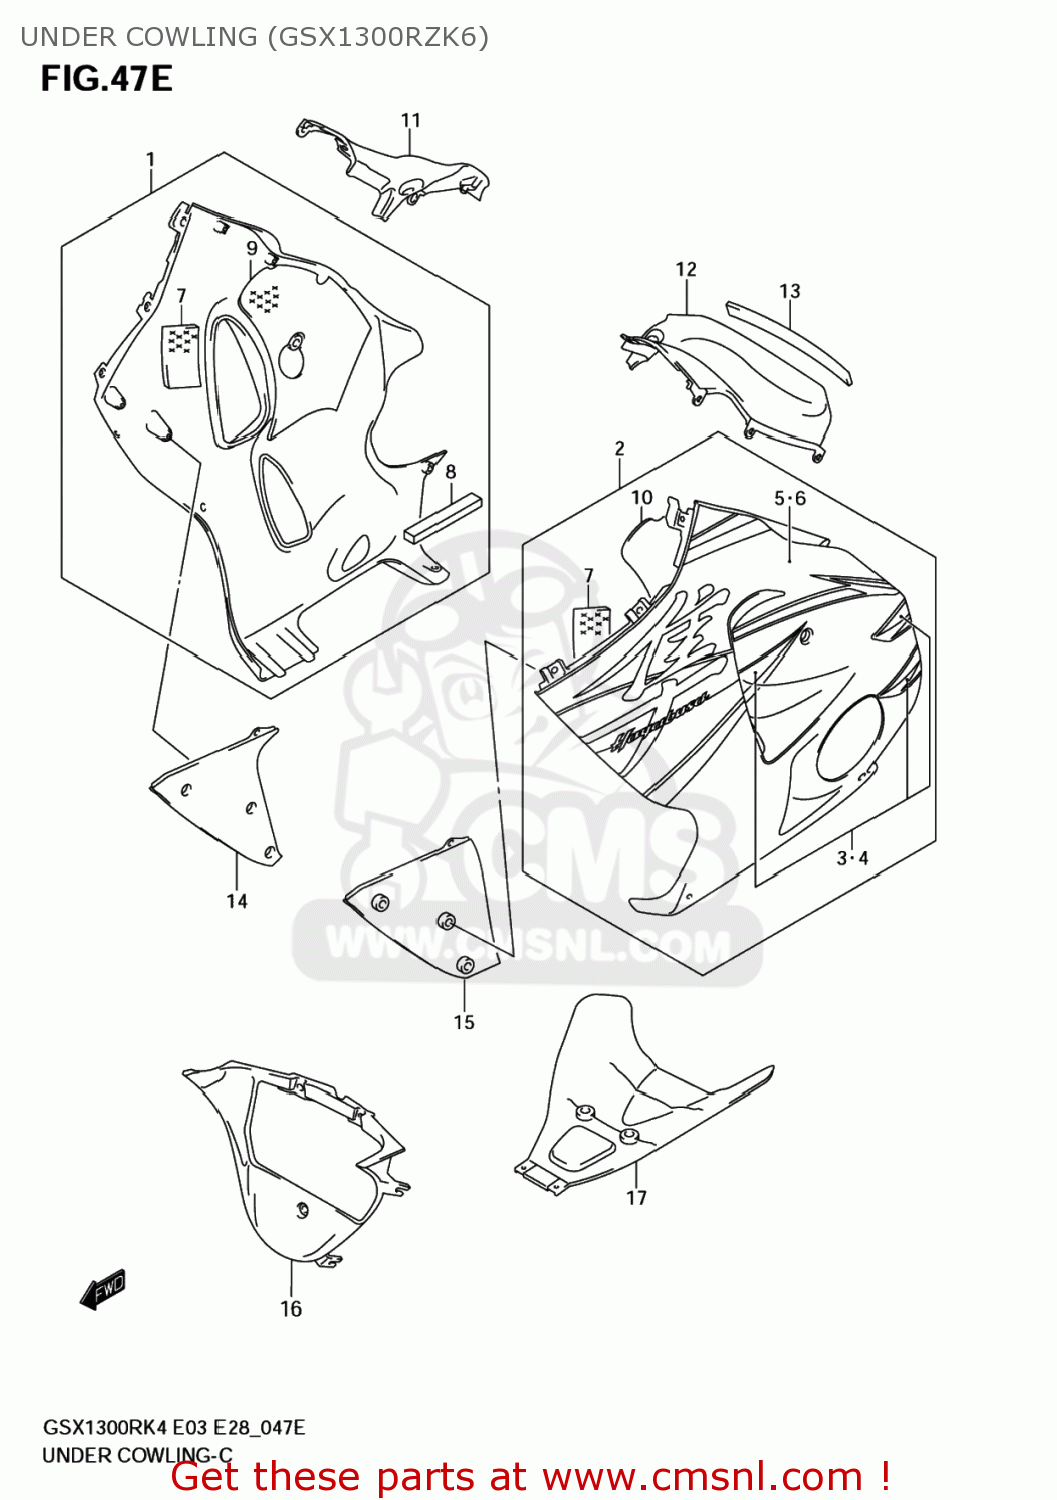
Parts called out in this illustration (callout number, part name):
1	COWL ASSY, UNDER RH (SILVER)
2	COWL ASSY, UNDER LH (SILVER)
3	TAPE SET,UNDER,R
4	TAPE SET,UNDER,L
5	TAPE,UNDER,R
6	TAPE,UNDER,L
7	CUSHION,UNDER COWLING NO,1
8	CUSHION,ENGINE COVER,RIGHT
9	CUSHION,UNDER COWLING NO.2,R
10	CUSHION,UNDER COWLING,L
11	PANEL,SIDE,R
12	PANEL,SIDE,L
13	MOLDING,SIDE PANEL
14	COWLING,UNDER INNER,R
15	COWLING,UNDER INNER,L
16	COWLING,UNDER CTR
17	COWLING,UNDER RR
